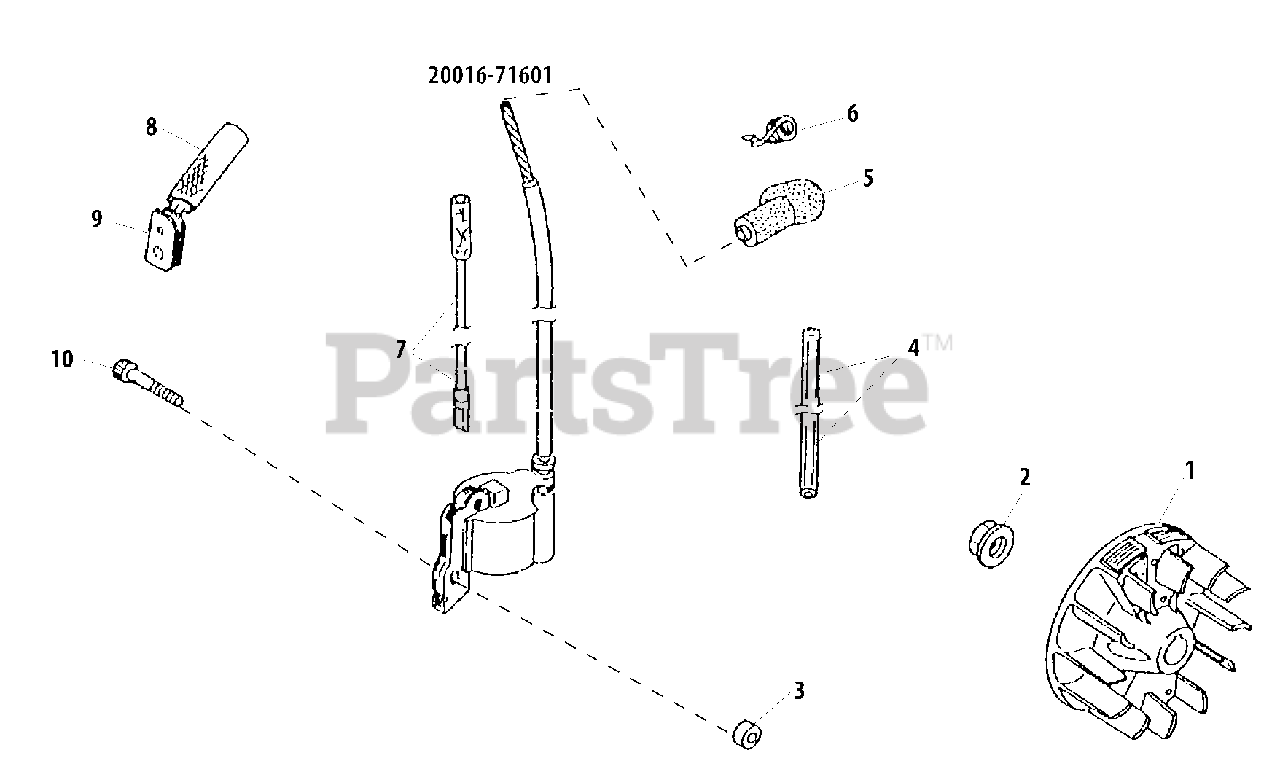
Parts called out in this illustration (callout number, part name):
1	FLYWHEEL
2	NUT - 8
3	INSULATOR
4	TUBE
5	CAP, SPARK PLUG
6	TERMINAL, SPARK PLUG CAP
7	LEAD - IGNITION
8	TUBE
9	GROMMET
10	SCREW - 4X26
20016-71601	IGNITION COIL ASSY
